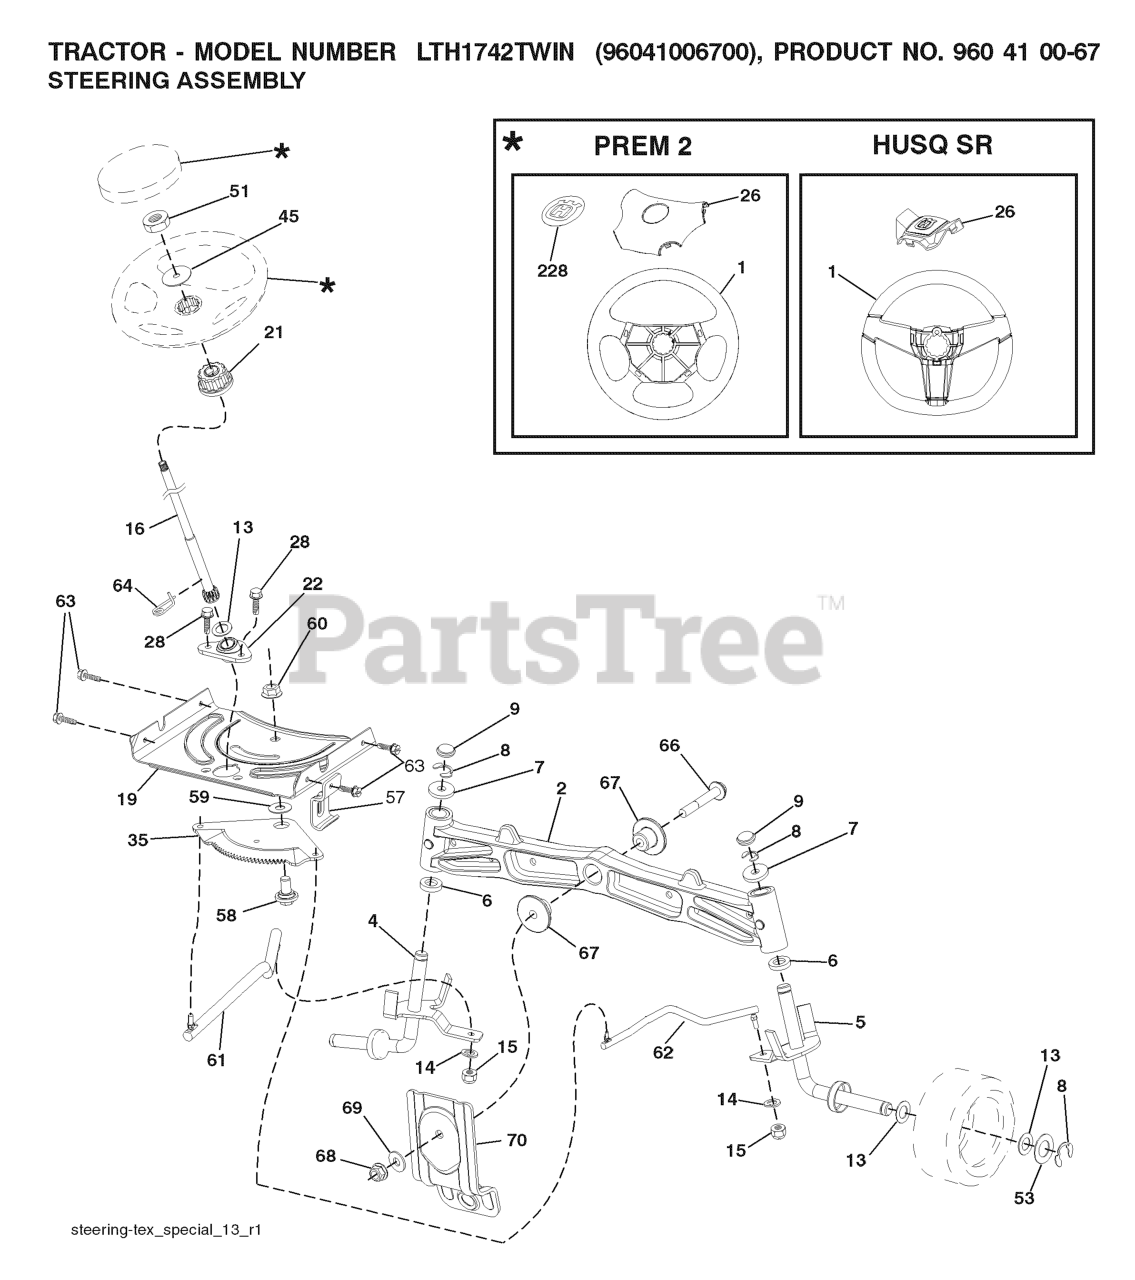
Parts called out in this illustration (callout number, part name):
1	RP WHEEL.STEER.HUSQ.PREM.OVMLD
2	AXLE ASSY FRONT
4	SPINDLE.WELDED.LH.15"TEX
5	SPINDLE.WELDED.RH.15"T
6	THRUST WASHER
9	CAP.SPINDLE.BLACK
14	WASHER, LOCK 3/8
15	NUT CROWNLOCK 3/8-24
16	SHAFT STEERING
19	PLATE.STEER.DDL.NLT/NG
20	BOOT, STEERING
21	ADAPTER, WHEEL STNG..
22	BUSHING.ASM.STEERING.A
26	RP INSERT.CAP.WHL.STRG.HUSQ.
28	SCREW, 3/8-16X3/4
33	WASHER.LOCK.HVY.HLCL.SPR.5/16
35	GEAR.SECTOR.PLATE.DDL.
45	WASHER.11/32
53	WASHER.HARDENED
57	BRACKET.UPSTOP.TEX
58	BOLT.SHOULDER.SECTOR.P
59	WASHER.THURST.SECTOR.S
60	NUT FLANGE LOCK 5/8-11
61	DRAGLINK.LH.BALLSTUD.D
62	DRAGLINK.RH.BALLSTUD.D
63	SCREW
64	RETAINER.CLIP.SPRING.S
66	BOLT HEX FGHD 7/16-14 X 3 SERR
67	BUSHING.PM.FRONT AXLE
68	NUT.LOCK.FLANGE.7/16
69	WASHER.1.5X.505X.118
70	BRKT.DECK.SUSPENSION.F
71	SHAFT EXTENSION STEERING
72	BOLT YT
228	DECAL.WHEEL.STRG.LGN.H
